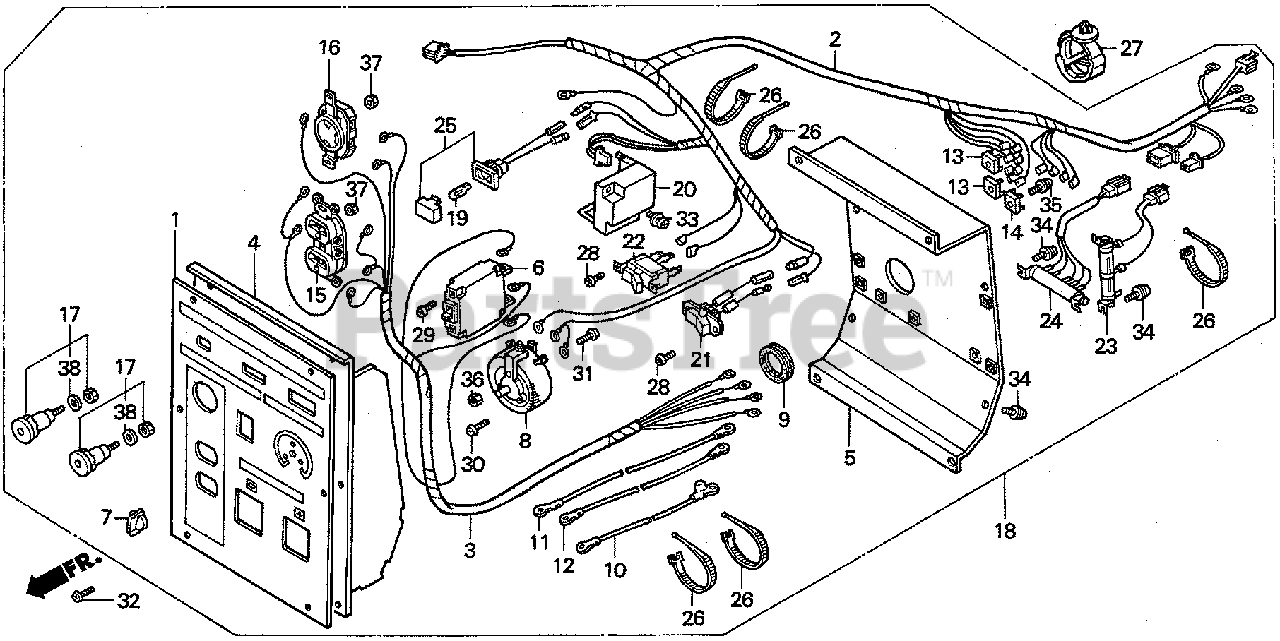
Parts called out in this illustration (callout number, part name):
1	PLATE, CONTROL INDICATION (EXW-A)
2	HARNESS ASSY., CONTROL (EXW-A)
3	HARNESS ASSY., A.C. OUTPUT (EXW-A)
4	PANEL, CONTROL (EXW-A)
5	COVER, CONTROL
6	BREAKER, CIRCUIT (33.5A)
7	KNOB, ADJUSTING
8	RESISTOR, VARIABLE
9	GROMMET, MAIN WIRE
10	WIRE ASSY. (+)
11	WIRE ASSY. (-)
12	WIRE ASSY. (REACTOR)
13	STACK, DIODE
15	RECEPTACLE (20A-125V)
16	RECEPTACLE (3-PRONG) (30A/125V)
17	RECEPTACLE, PANEL
18	PANEL ASSY., CONTROL (EXW-A)
19	BULB, WEDGE BASE (12V/2W) (TSD30) (STANLEY)
20	THROTTLE UNIT ASSY., AUTO
21	SWITCH ASSY., AUTO THROTTLE
22	SWITCH ASSY.
23	RESISTOR, ADJUSTABLE
25	SOCKET ASSY., LAMP (GREEN)
26	TIE, CABLE
27	CLIP, HARNESS
28	SCREW, PAN (3X6)
29	SCREW, PAN (4X6)
30	SCREW, PAN (4X10)
31	SCREW, PAN (4X10)
32	SCREW, PAN (5X10)
33	SCREW-WASHER (5X12)
34	SCREW-WASHER (4X10)
35	SCREW-WASHER (4X20)
36	NUT, HEX. (4MM)
37	NUT, FLANGE (4MM)
38	WASHER, PLAIN (8MM)
